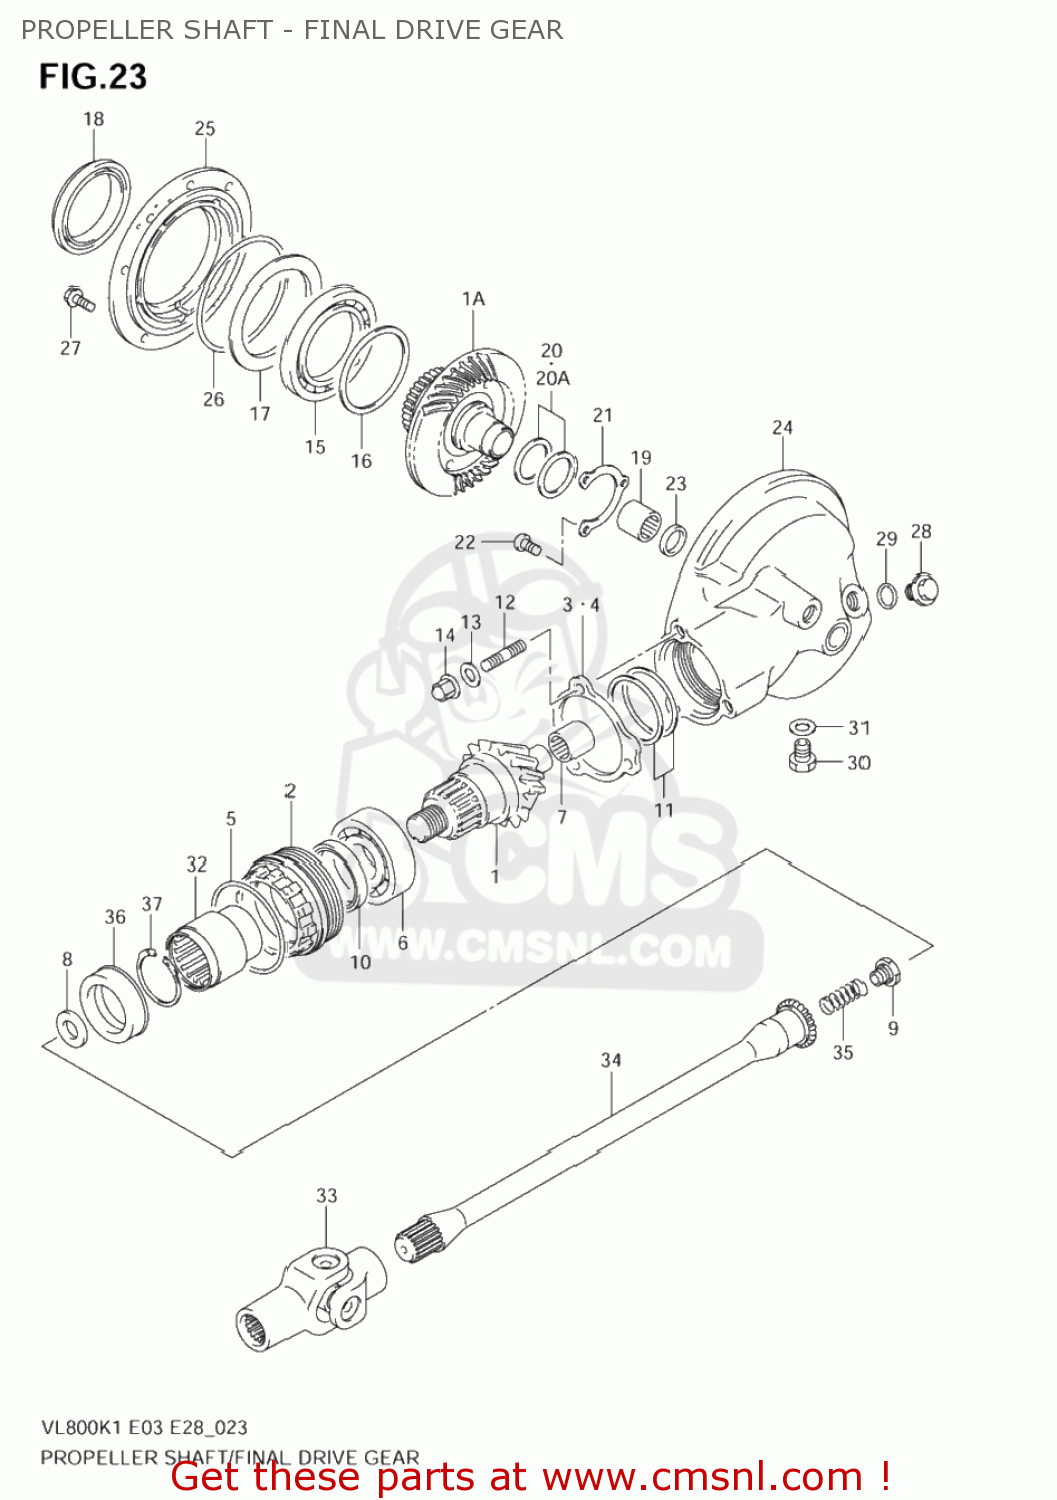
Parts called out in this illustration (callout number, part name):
1	GEAR,FINAL DRIVE BEVEL(NT:11)
1A	GEAR,FINAL DRIVEN BEVEL(NT:34)
2	STOPPER,FINAL DRIVE BEARING
3	PLATE,BEARING STOPPER
4	PLATE,BEARING STOPPER
5	O RING(D:1.9,ID:61.6)
6	BEARING(30X62X23.8)
7	BEARING(17X32X16)
8	WASHER(16X29X4)
9	NUT
10	SEAL,OIL(38X54X6)
11	SHIM SET,FINAL DRIVE GEAR
12	BOLT,STUD
13	WASHER
14	NUT
15	BEARING(70X110X13)
16	SHIM SET,DRIVEN GEAR BEARING
17	PLATE,FINAL DRIVEN BRG OIL
18	SEAL,OIL(70X96X16)
19	BEARING(32X46X17.7)
20	SHIM SET,FINAL DRIVEN GEAR
20A	SHIM SET,FINAL DRIVE GEAR
21	RETAINER,FINAL DRIVEN GEAR BRG
22	SCREW
23	SEAL,OIL(30X42X7)
24	CASE,FINAL
25	CASE,FINAL GEAR BEARING
26	O RING(D:3.5,ID:131.6)
27	BOLT
28	PLUG
29	O RING(D:2.4,ID:17.8)
30	PLUG(MAGNETO)
31	GASKET(13.8X18.8X4.8) (NAS)
32	COUPLING,FINAL DRIVE GEAR
33	YOKE COMP,UNIVERSAL JOINT
34	SHAFT,PROPELLER
35	SPRING
36	SEAL,OIL(28.4X48X15)
37	CIRCLIP
